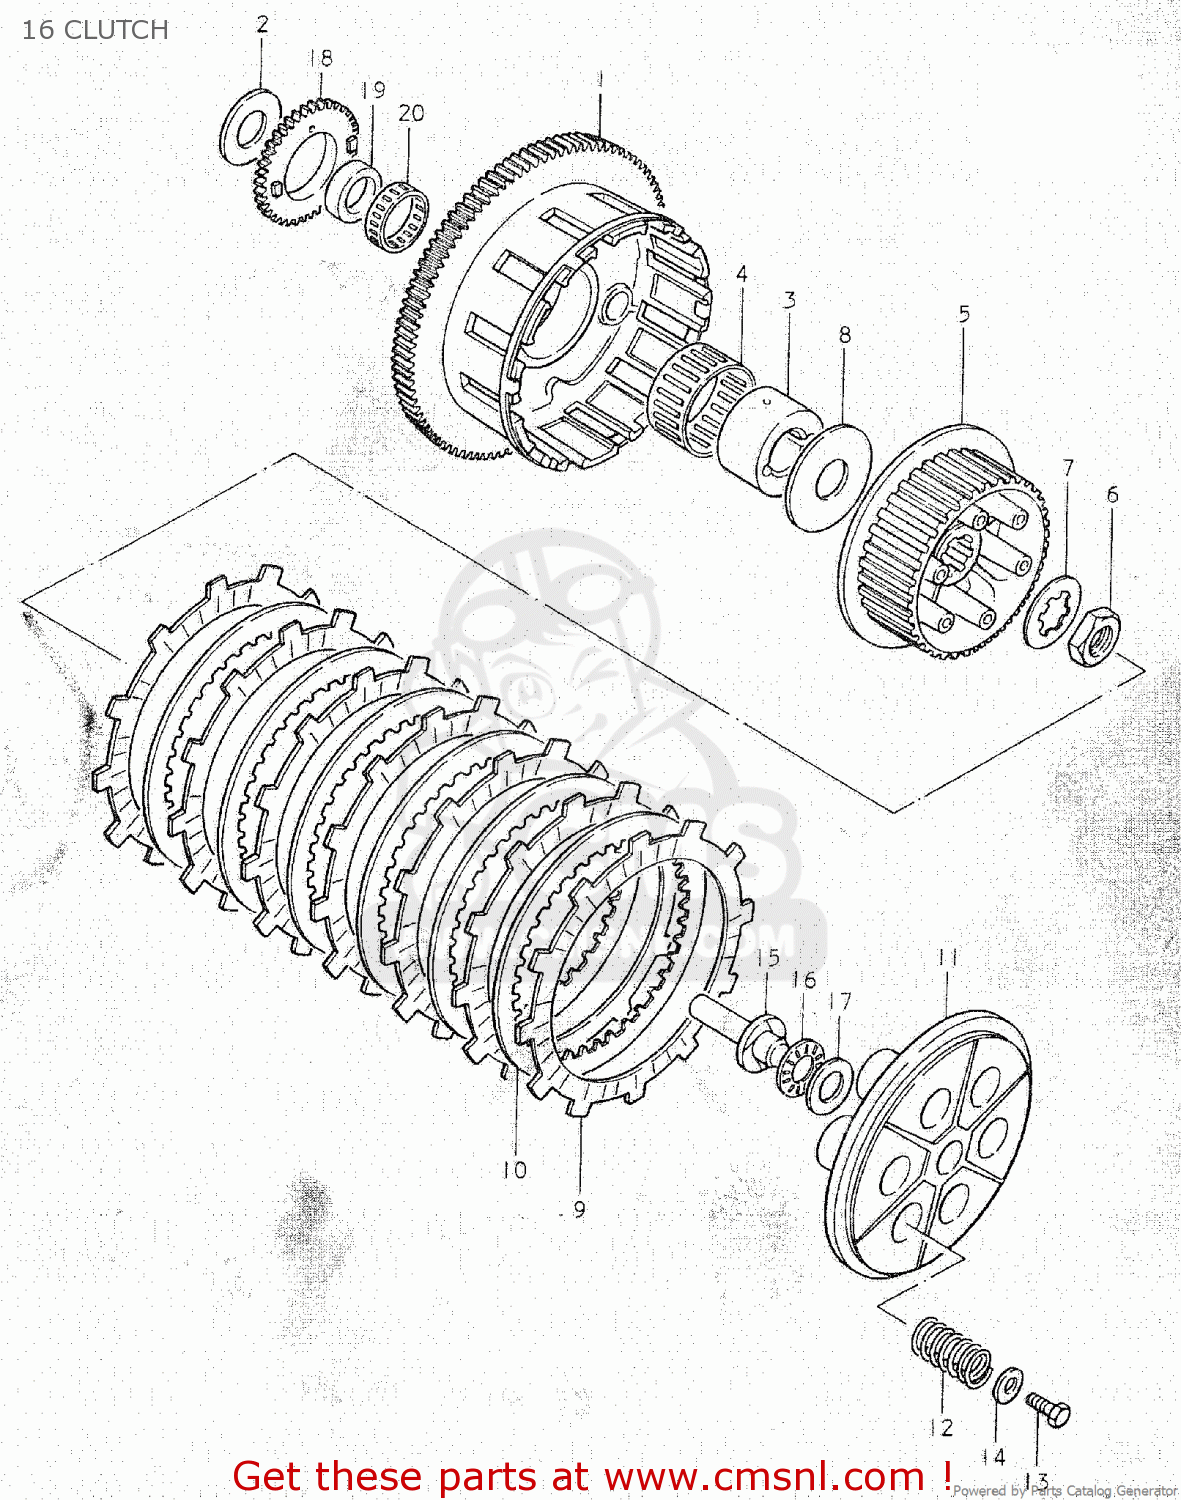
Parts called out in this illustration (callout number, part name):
1	GEAR ASSEMBLY,PRIMARY DRIVE
2	WASHER
3	SPACER,PRIMARY DRIVEN
4	BEARING
5	HUB,CLUTCH SLEEVE
6	NUT
7	WASHER,LOCK
8	WASHER(25X66X3.5)
9	PLATE,CLUTCH DRIVE (NAS)
10	PLATE,CLUTCH DRIVEN (NAS)
11	DISC,CLUTCH PRESSURE
12	SPRING
13	BOLT, UPPER
14	WASHER
15	PIECE,CLUTCH PUSH
16	BEARING(15X28X2)
17	WASHER
18	GEAR,ENG OIL PUMP DRIVE(NT:38)
19	SPACER,OIL PUMP DRIVE GEAR
20	BEARING(36X40X10)
